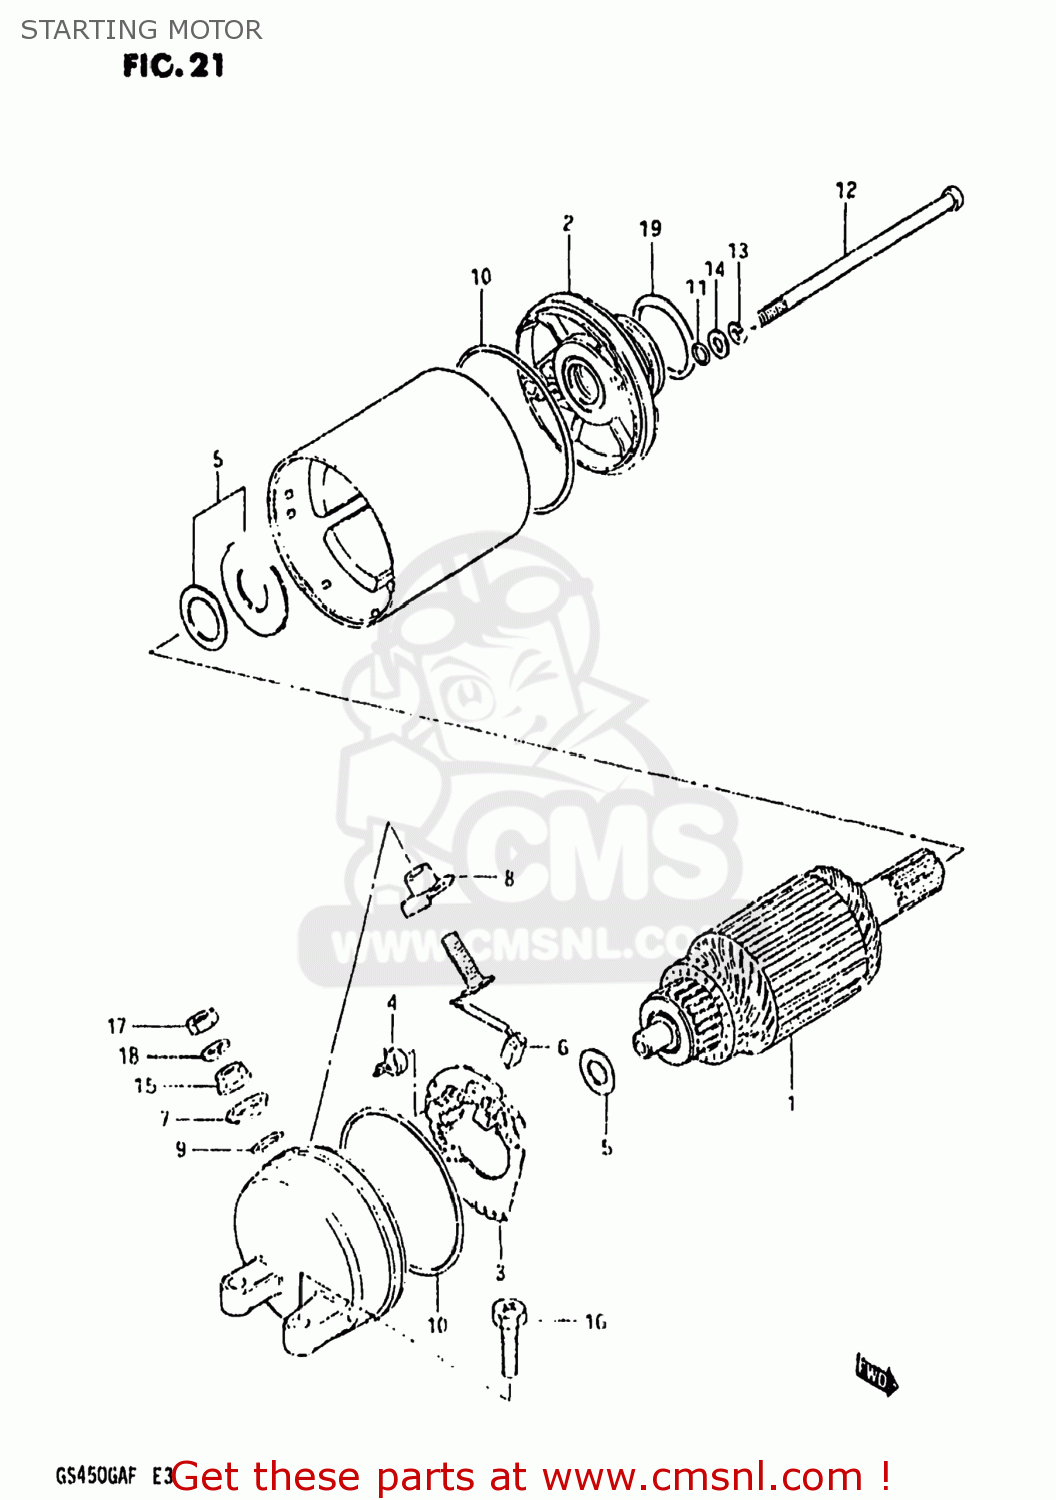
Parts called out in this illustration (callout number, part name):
1	ARMATURE
2	BRACKET SET,STARTING MOTOR
3	HOLDER,BRUSH
4	SPRING
5	SHIM SET,STARTING MOTOR
6	BRUSH SUB ASSY,STARTING MOTOR
7	BUSHING
8	BUSH,B
9	O RING
10	O RING
11	O RING
12	BOLT
13	LOCK WASHER
14	WASHER
15	NUT
16	SCREW (6X25)
17	NUT
18	WASHER,LOCK
19	O RING(D:3,ID:24.5)
